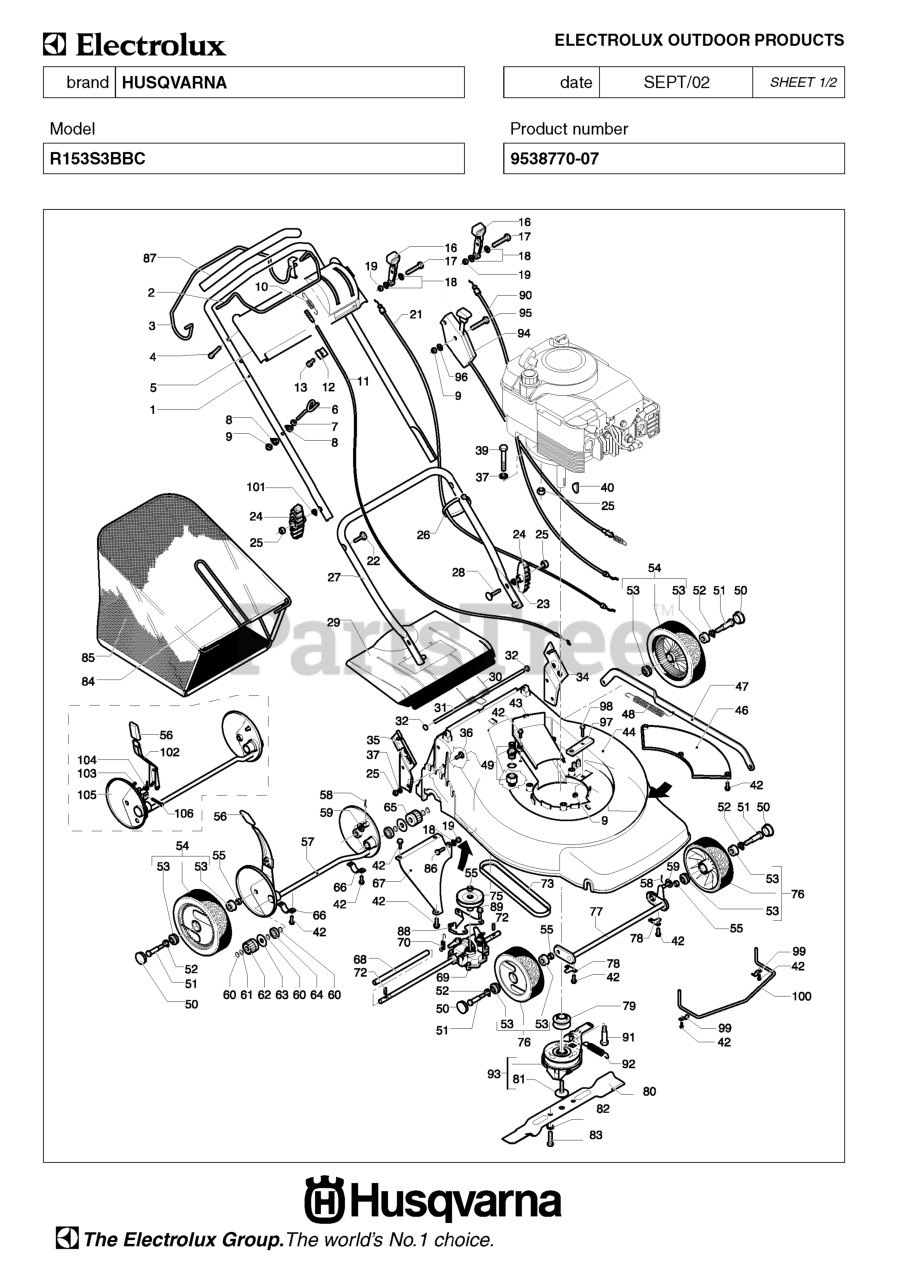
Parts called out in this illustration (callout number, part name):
28	Screws
42	Screws
58	Pins
60	Washers
